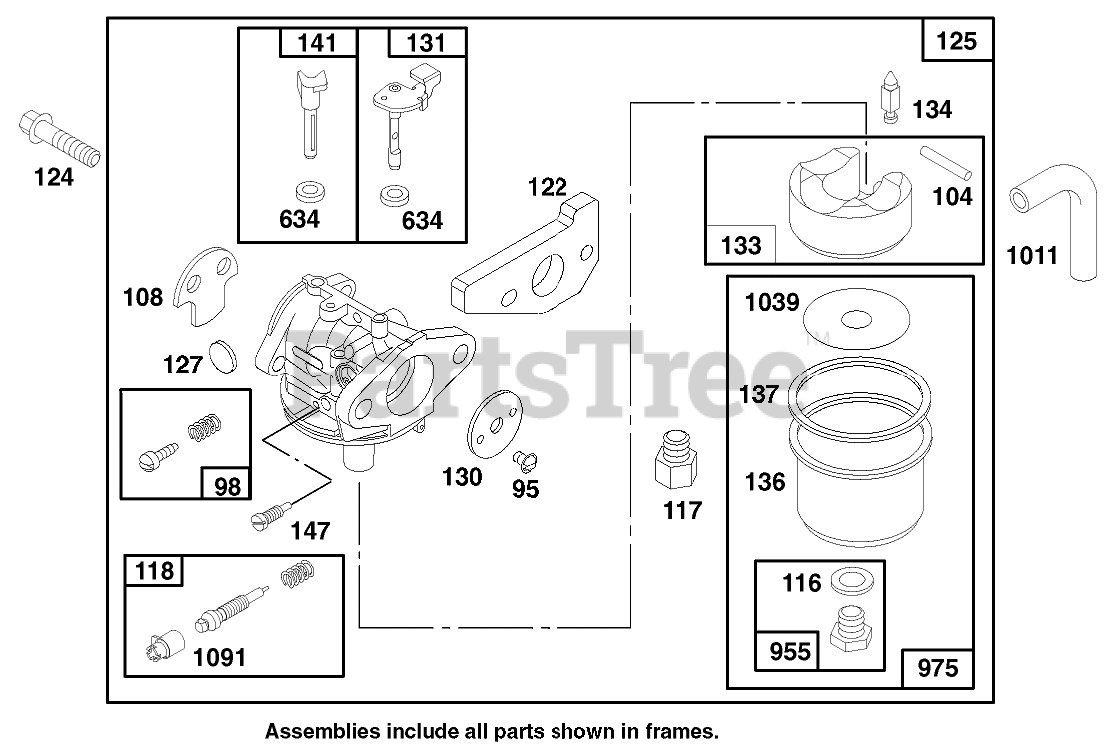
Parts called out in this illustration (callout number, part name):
95	SCREW - ROUND HEAD
98	IDLE ADJUSTING SCREW
104	FLOAT HINGE PIN
108	VALVE - CHOKE
116	SEALING GASKET
117	Jet-Main
118	VALVE/SPRING - NEEDLE
122	ADAPTER ASSEMBLY
124	HEX HEAD SCREW
125	ASSEMBLY - CARBURETOR
127	PLUG
130	THROTTLE VALVE
131	THROTTLE SHAFT
133	FLOAT-CARBURETOR
134	Valve-Inlet (Includes Seat)
136	FLOAT BOWL
137	FLOAT BOWL GASKET
141	CHOKE SHAFT
147	JET - PILOT
621	STOP SWITCH
634	SEAL WASHER
955	HEX HEAD SCREW
975	CARBURETOR BOWL ASM
1011	VENT TUBE
1039	FLOAT LIMITER
1091	CAP - LIMITER
